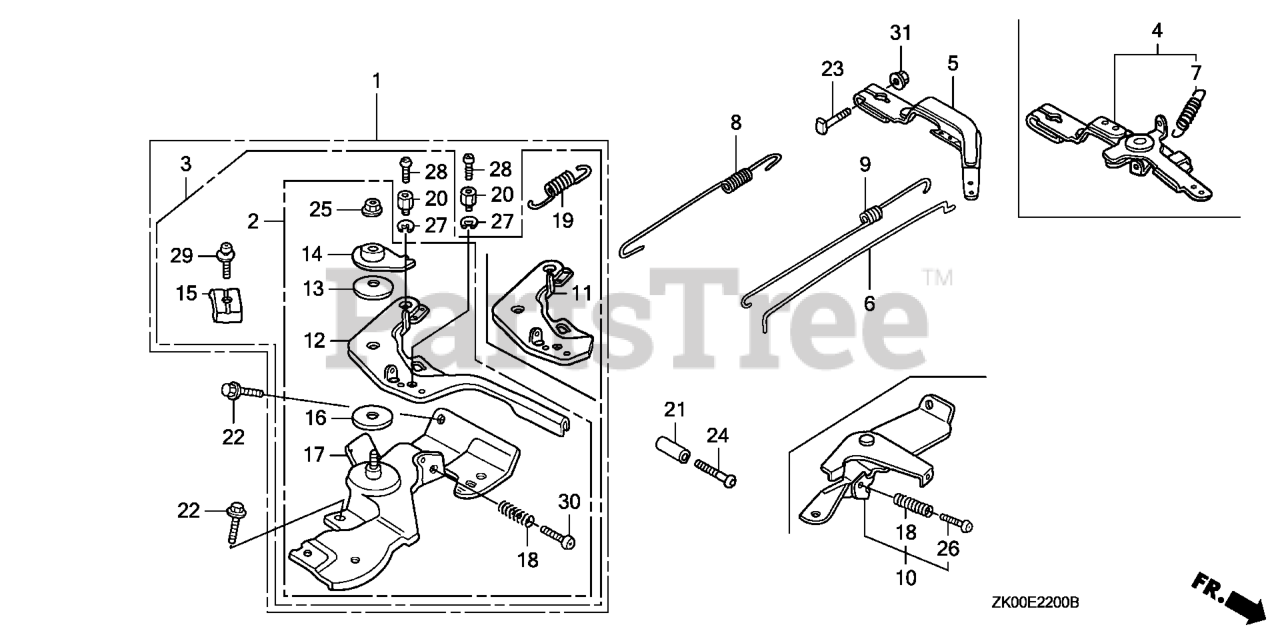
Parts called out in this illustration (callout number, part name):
2	CONTROL ASSY.
5	ARM, GOVERNOR
6	ROD, GOVERNOR
8	SPRING, GOVERNOR
9	SPRING, THROTTLE RETURN
12	LEVER, CONTROL
13	SPRING, LEVER
14	WASHER, CONTROL LEVER
16	SPACER, CONTROL LEVER
17	BASE, CONTROL Use from Engine SN 3172542.
18	SPRING, CONTROL ADJUSTING Use from Engine SN 2327377.
22	BOLT, FLANGE (6X12) (CT200)
23	BOLT, GOVERNOR ARM
25	NUT, SELF-LOCK (6MM)
30	SCREW, PAN (5X25)
31	NUT, FLANGE (6MM)
